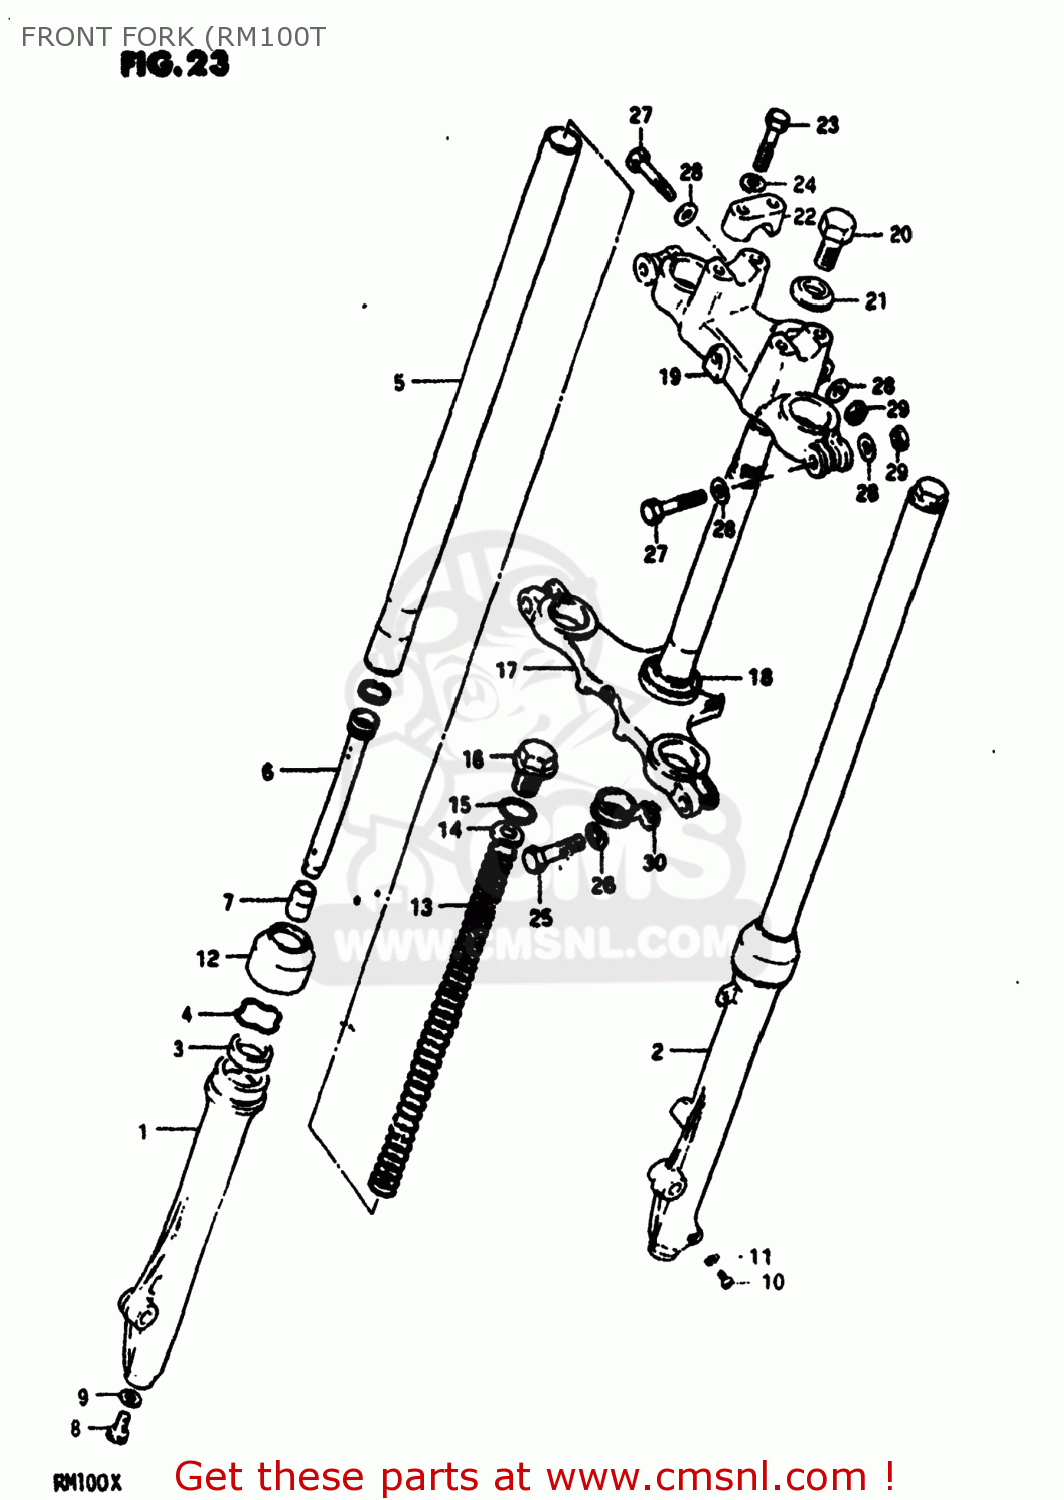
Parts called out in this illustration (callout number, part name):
0	DAMPER SET
1	TUBE,OUTER,RIGHT
2	TUBE,OUTER,LEFT
3	SEAL,OIL
4	5
5	TUBE,FORK,INNER
6	CYLINDER,FRONT FORK
7	PIECE,OIL LOCK
8	BOLT,FORK CYLINDER(10X25)
9	GASKET (NAS)
10	SCREW
11	GASKET,DRAIN,PLUG (NAS)
12	SEAL,DUST
13	SPRING
14	GUIDE,FRONT FORK SPRING C
15	O RING
16	CAP,FORK INNER TUBE
17	STEM,STEERING
18	RACE,STEERING,OUTER,UPPER
19	HEAD,STEERING STEM
20	BOLT
21	WASHER
22	HOLDER,HANDLEBAR
23	BOLT
24	LOCK WASHER
25	BOLT
26	WASHER,LOCK 12
27	BOLT 8X55
28	WASHER
29	NUT 8MM
30	GUIDE,CABLE
